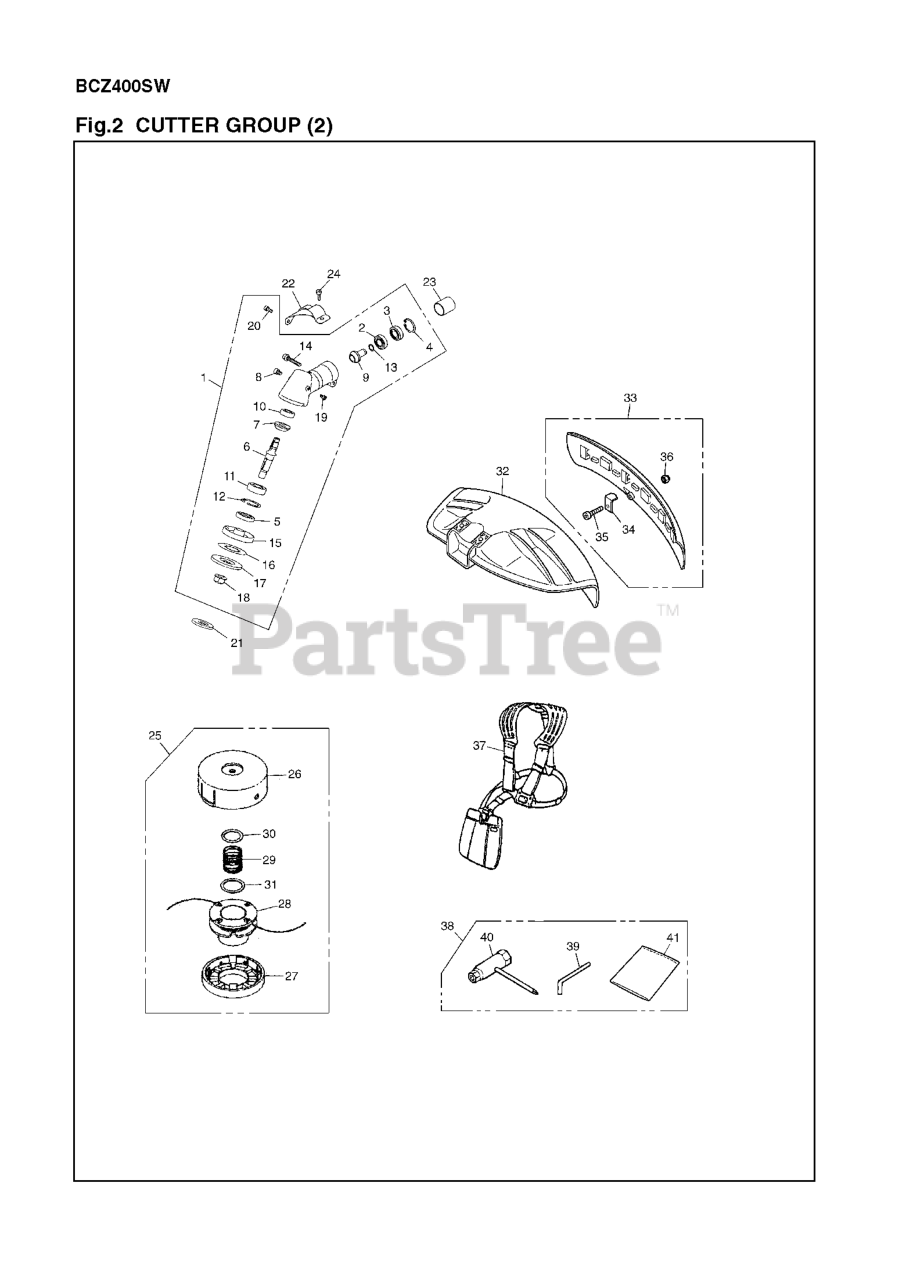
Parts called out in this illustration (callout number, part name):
1	GEAR CASE ASSY
3	BEARING,10MM ID,26MM OD,8MM W
4	RING,SNAP M26x1.2 RP-318013340
8	BOLT,TORX M6X8
11	BEARING,12MM ID,28MM OD, 8MM W
13	RING, SNAP, M10 x 1.0
14	BOLT,TORX
15	HOLDER (A)
17	HOLDER (B)
20	BOLT M5X14
24	BOLT,TORX M6X30
25	6" TAP HEAD PT100
26	CASE
28	CORD HOLDER
33	GUARD ASSY
37	HARNESS ASSY (RPLS-17201) Acc
38	TOOL SET (RPLS 848-8UD-0120)
40	SOCKET
